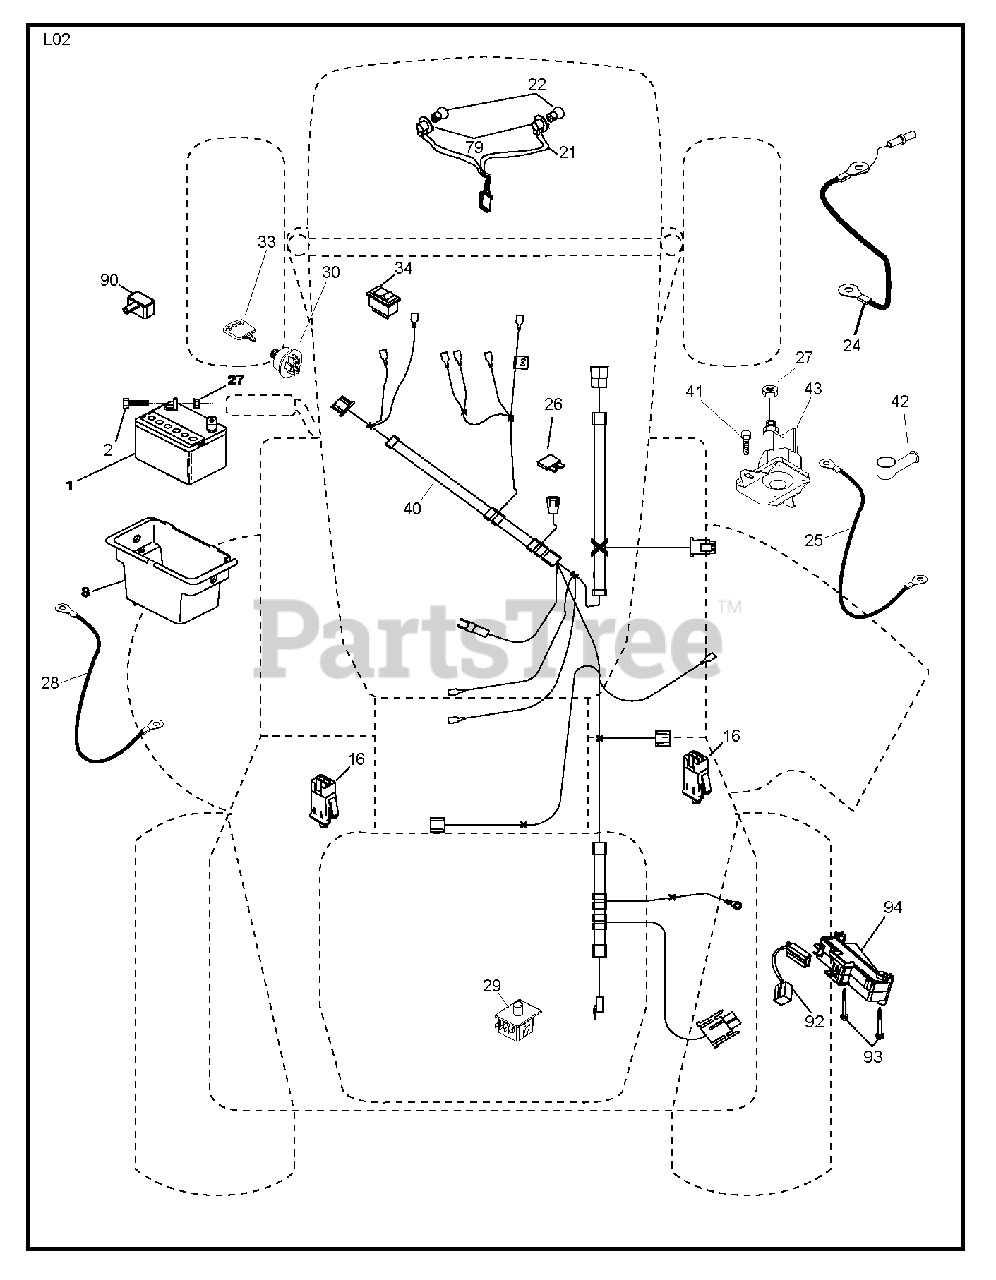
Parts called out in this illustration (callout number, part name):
1	REPL BY 532 12 38-99
2	BOLT.HEX.1/4.X.3/4.DICHROMATE
8	BOX.BATTERY.FENDER
16	SWITCH INTERLOOK PUSH-IN
21	HARNESS ASSY LIGHT
22	LIGHTBULB
24	CABLE.STARTER.6GA.11"RED
25	CABLE.GROUND.REAR.BTRY.8GA.44"
26	FUSE 20AMP
27	NUT
28	CABLE GROUND 6 GA. 12" BLACK
29	SWITCH.SEAT.DP W/RAMPS
30	SWITCH.IGN.DELTA.W.LGH.ROS
33	KEY.CHAIN.BLISTER.PACK.GEN.INT
34	SWITCH LT
40	HARNESS.IGN.CABLE.REG.
41	BOLT
42	TERMINAL COVER
43	SOLENOID.W/BRASS.PLUNGER
79	BULB HOLDER ASM.
90	COVER.TERMINAL.BATTERY
92	HARNESS.PIGTAIL.CONSLE
93	SCREW.PLASTITE
94	MODULE.REVERSE.ROS
